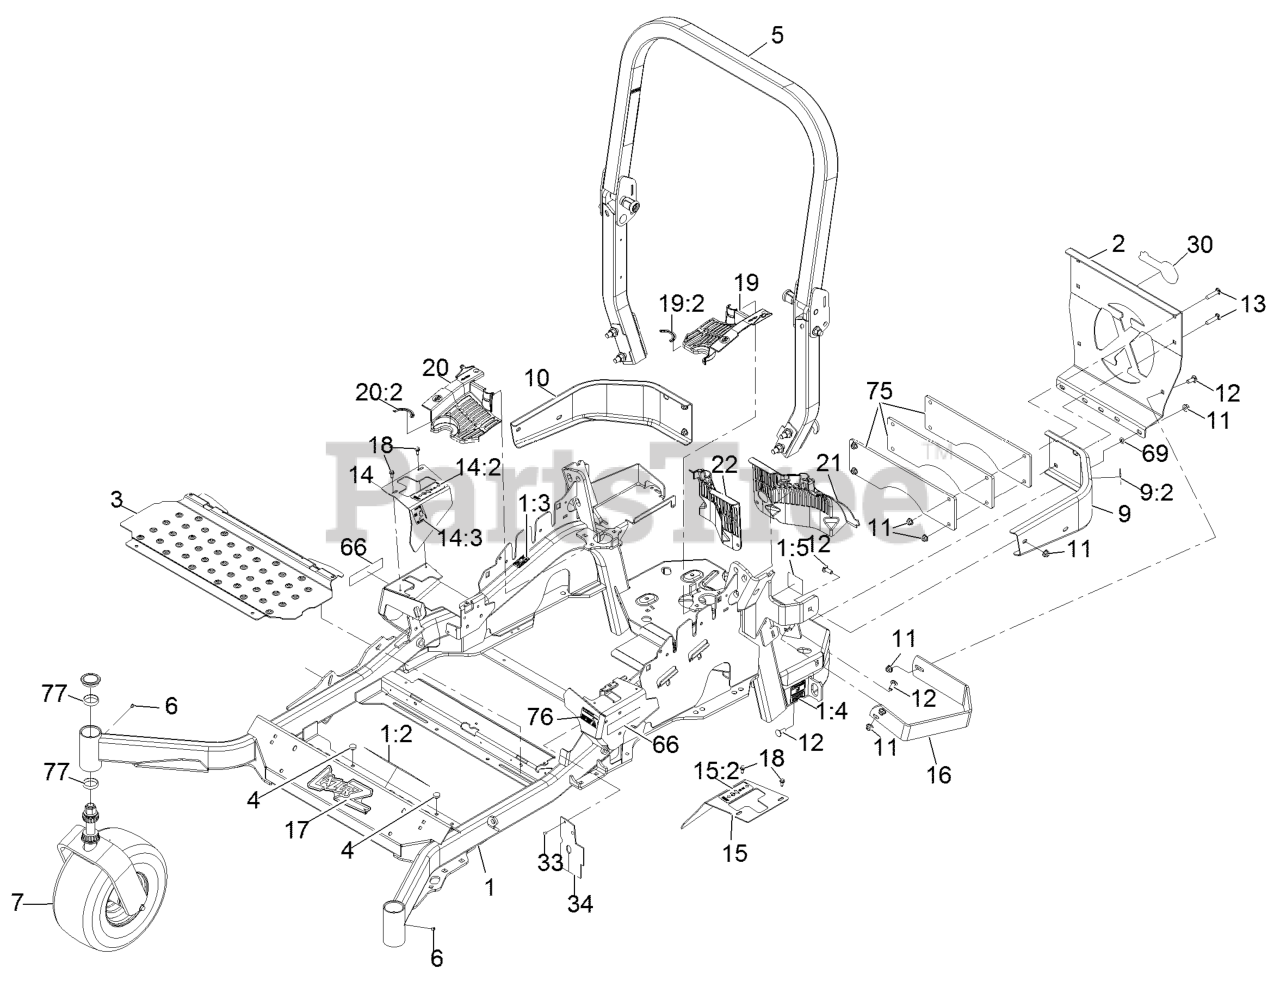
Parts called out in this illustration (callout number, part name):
1	MAINFRAME ASM
1:2	DECAL-CAUTION
1:3	DECAL-SLOPE
1:4	DECAL-BELT DRIVE
1:5	DECAL-SPARK ARRESTER
2	PLATE,REAR GUARD
5	ASM,ROPS SERVICE EXMARK
7	Caster Wheel Asm
9	LH BUMPER ASM
9:2	DECAL-CAUTION
10	BUMPER-RH
11	NUT-HF, NI
12	SCREW-CARR
13	SCREW-CARR
14	RH MOTION CONTROL COVER ASM
14:2	DECAL-MOTION CONTROL
14:3	DECAL-PARK BRAKE
15	LH MOTION CONTROL COVER ASM
15:2	DECAL-MOTION CONTROL
16	GUARD-MUFFLER
17	DECAL,LAZER MODEL
18	SCREW-HWH
19	LH HYDRO GUARD ASM
19:2	DECAL-HYDRO OIL
20	RH HYDRO GUARD ASM
20:2	DECAL-HYDRO OIL
21	GUARD-HYDRO, REAR (LH)
22	GUARD-HYDRO, REAR (RH)
33	RIVET-POP
34	DEFLECTOR-AIR FLOW
66	DECAL-S-SERIES
69	NUT-PUSH
76	DECAL-FUEL FILL
77	CUP-BEARING
